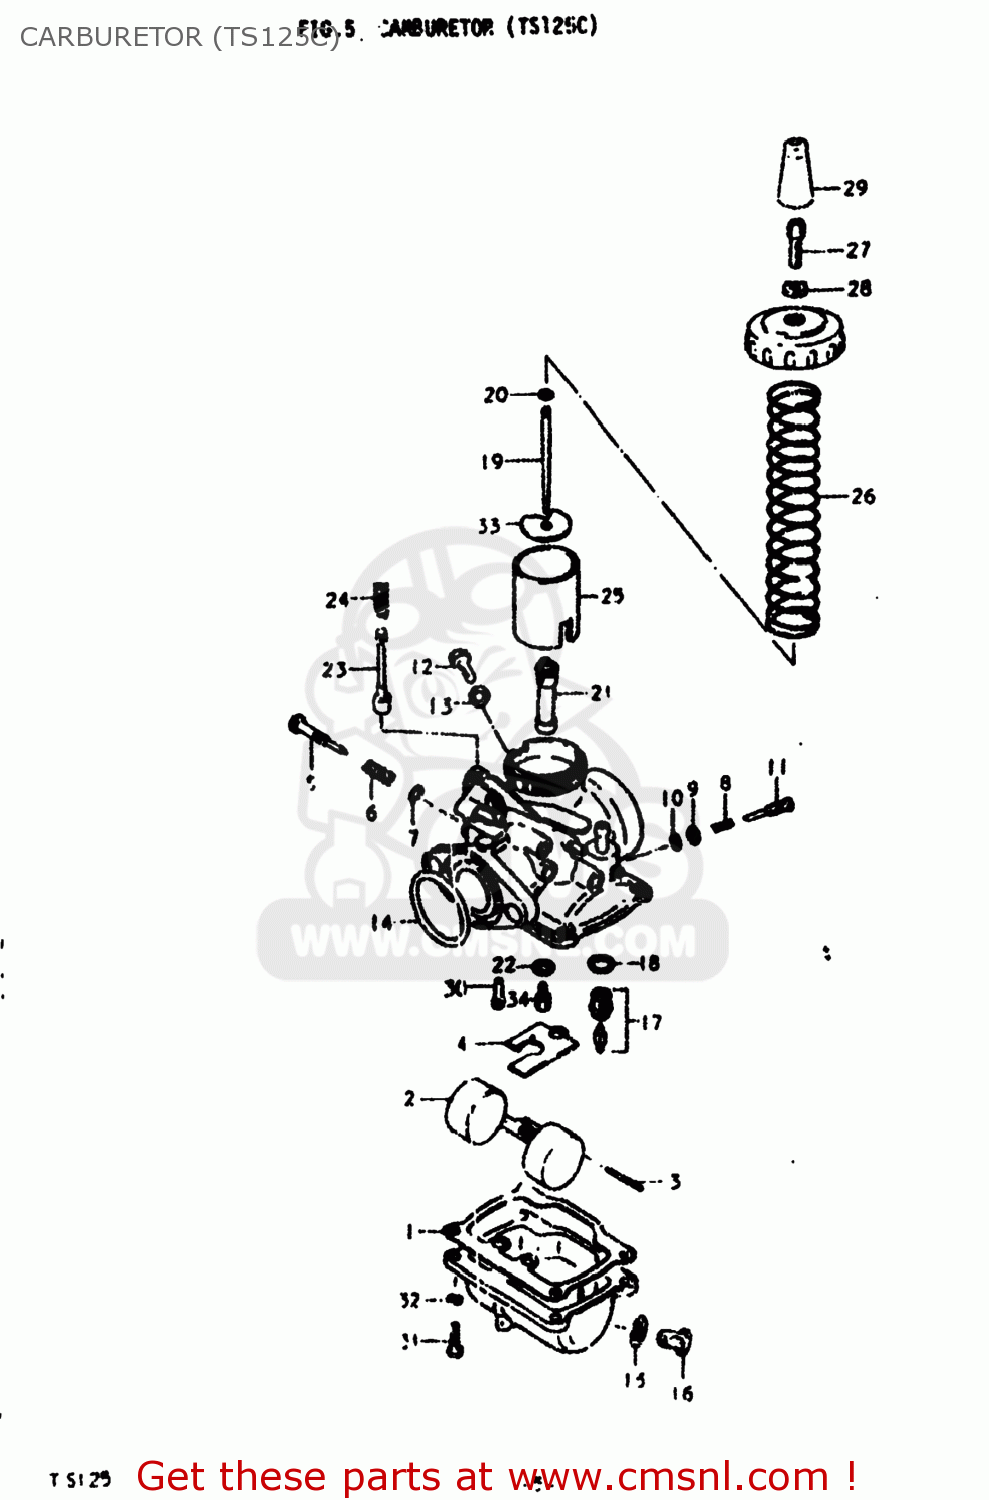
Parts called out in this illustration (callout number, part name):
0	CARBURETOR ASSEMBLY
1	GASKET,FLOAT CHAMBER (NAS)
2	FLOAT
3	PIN,FLOAT
4	PLATE
5	SCREW,THROTTLE STOP
6	SPRING,PILOT
7	O-RING
8	SPRING
9	WASHER,PILOT AIR SCREW
10	O RING
11	SCREW,PILOT AIR
12	BOLT
13	GASKET,THRO VALVE INSPECTION (NAS)
14	O RING
15	GASKET,DRAIN,PLUG (NAS)
16	PLUG
17	VALVE ASSEMBLY,NEEDLE
18	GASKET,VALVE SEAT (NAS)
19	NEEDLE,JET
20	CLIP
21	JET,NEEDLE
22	WASHER
23	VALVE,STARTER
24	SPRING
25	VALVE,THROTTLE
26	SPRING, THROTTLE VALVE
27	ADJUSTER,CABLE
28	NUT
29	CAP
30	JET
31	SCREW
32	LOCK WASHER
33	SEAT,THROTTLE VALVE SPRING
34	JET,MAIN 85
